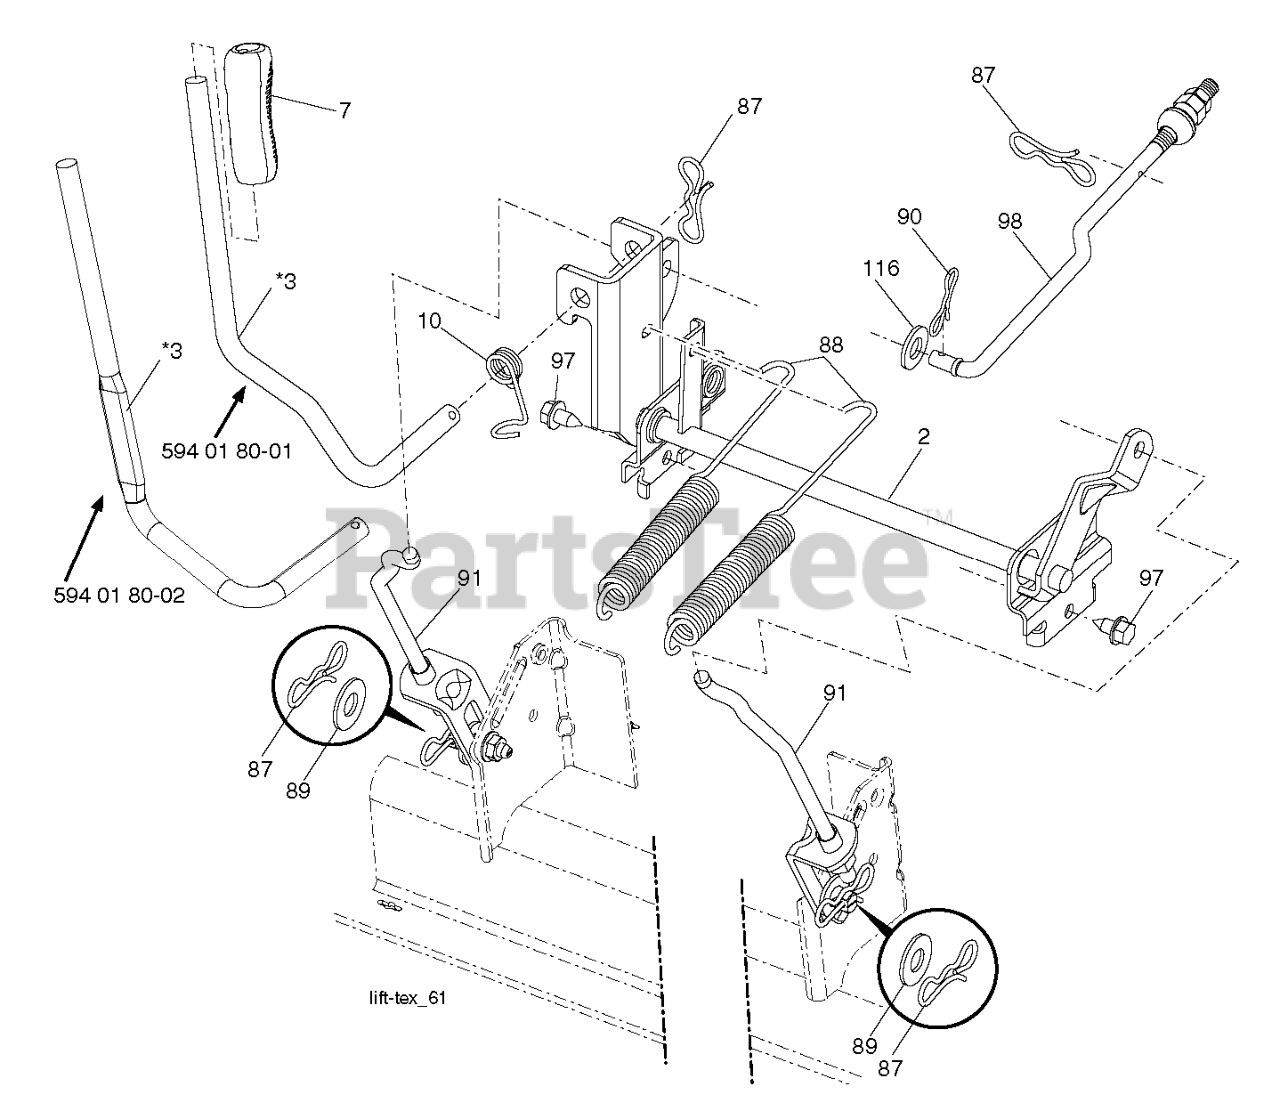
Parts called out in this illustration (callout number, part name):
2	SHAFT.ASM.CROSS.LIFT
7	GRIP.HANDLE.LIFT.PVC.BLACK
10	SPRING.TORSION.LIFT.HANDLE
87	PIN.COTTER.7/16.BOW TI.
88	SPRING.LIFT.ASSIST
89	WASHER.CLEAR.ZINC
90	PIN.COTTER.5/16.BOW TI
97	SCREW, 3/8-16X3/4
116	WASHER
116	WASHER.CLEAR.ZINC
